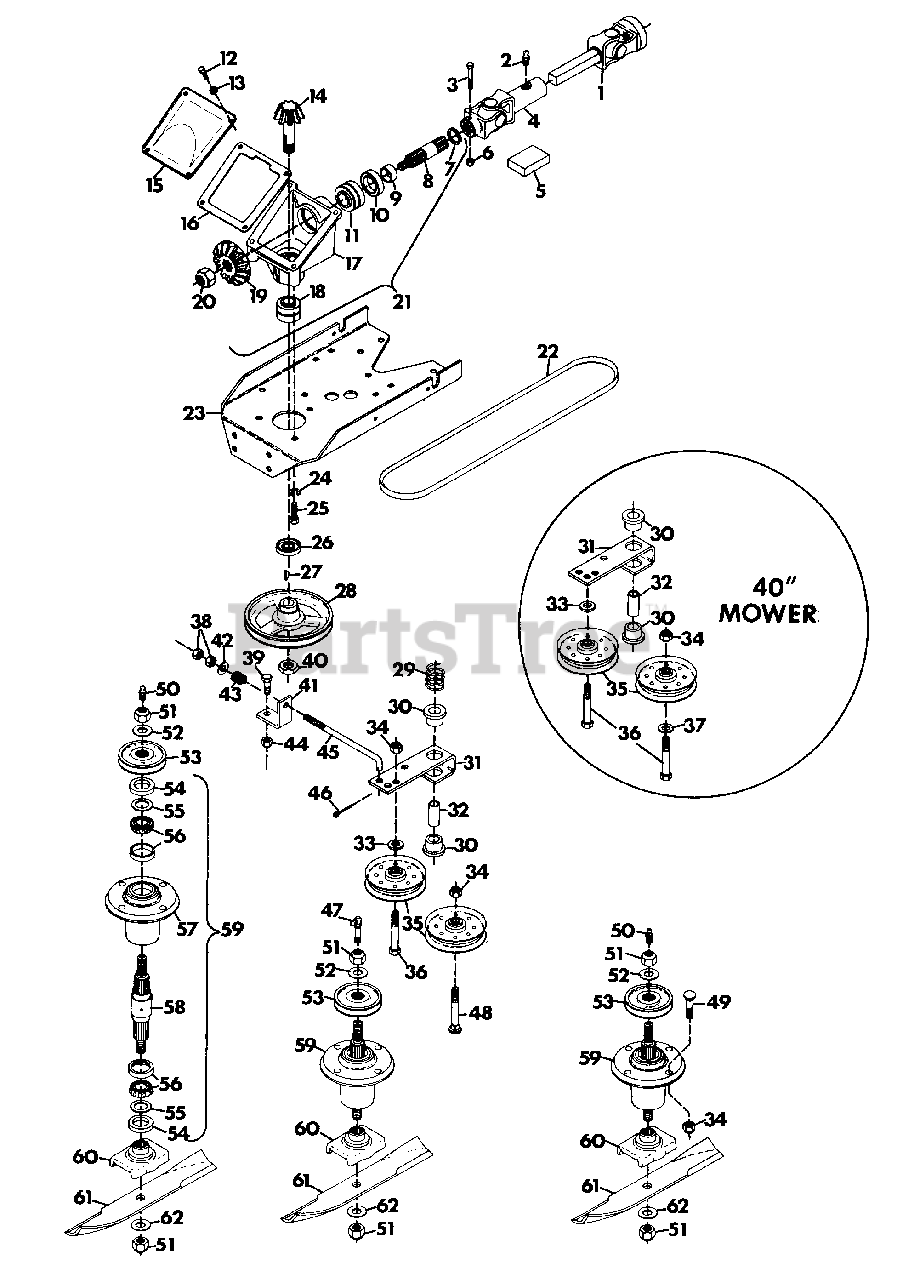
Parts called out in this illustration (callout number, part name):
1	SHAFT, PROP. SQ. BAR
2	FITTING, LUBE 1/4-28
3	BOLT, HEX 1/4-20X2
4	U-JOINT, FEMALE END
5	KIT, REPAIR U-JOINT(ROCK. STD.)
5	KIT, REPAIR U-JOINT(NEAPCO)
6	NUT, LOCK 1/4-20
7	RING, RETAINING 1.000 SHAFT
8	SHAFT, DRIVE
9	SPACER
10	SEAL, OIL 1.250X1.987X.250
11	ASSEMBLY, BEARING 1.000X1.980X1.243
12	BOLT, HEX 1/4-20X.50
13	WASHER, LOCK 1/4 REG.
14	SHAFT, GEAR PINION
15	COVER, GEAR HOUSING
16	GASKET, GEAR HOUSING
17	CASTING, GEAR BOX
18	ASSEMBLY, BEARING .750X1.781X1.499
19	GEAR, BEVEL
20	NUT, LOCK 3/4-10
21	ASSEMBLY, DRIVE
22	BELT, 40" MOWER
23	SUPPORT, GEAR HOUSING
24	WASHER, LOCK 1/2 REG.
25	BOLT, HEX 1/2-13X1
26	SEAL, OIL 1.250X1.686X.313
27	KEY, WOODRUFF .188X.625 HARD #61
28	SHEAVE, 1/2X6.50
29	SPRING, COMP.
30	BUSHING, NYLON .760X1.000X.600
31	ARM, IDLER PIVOT
32	SPACER
33	SPACER, IDLER .406X.750X.188
34	NUT, LOCK 3/8-16
35	SHEAVE, IDLER
36	BOLT, HEX 3/8-16X2.00
37	WASHER, FLAT .438X1.000X.083
38	NUT, HEX 3/8-24
39	BOLT, HEX 1/2-13X1.50
40	NUT, JAM 3/4-10 HEX HEAVY
41	SUPPORT, SPRING
42	WASHER, FLAT .406X.812X.065
43	SPRING, COMP. 1X.78X338 LB/IN
44	NUT, LOCK 1/2-13
45	ROD, IDLER 50" MOWER
45	ROD, IDLER 40" MOWER
46	PIN, COTTER 3/32X1.00
47	FITTING, LUBE .125 EXT. 90 DEG.
48	BOLT, 3/8-16X1.75 RD HD SQ NK
49	BOLT, 3/8-16X1.25 RD HD SQ NK
50	FITTING, LUBE 1/8
51	NUT, LOCK 5/8-11
52	WASHER, FLAT .687X1.312X.122/.146
53	SHEAVE, SPINDLE 40" MOWER
53	SHEAVE, SPINDLE 50" MOWER
54	SEAL, STEEL
55	WASHER, FLAT .975X1.970X.030
56	ASSEMBLY, BEARING
57	HOUSING, BEARING
58	SHAFT, SPINDLE
59	ASSEMBLY, SPINDLE
60	WELDMENT, BLADE CRADLE
61	BLADE, 50" MOWER(STANDARD)
62	WASHER, FLAT .656X1.312X.095
